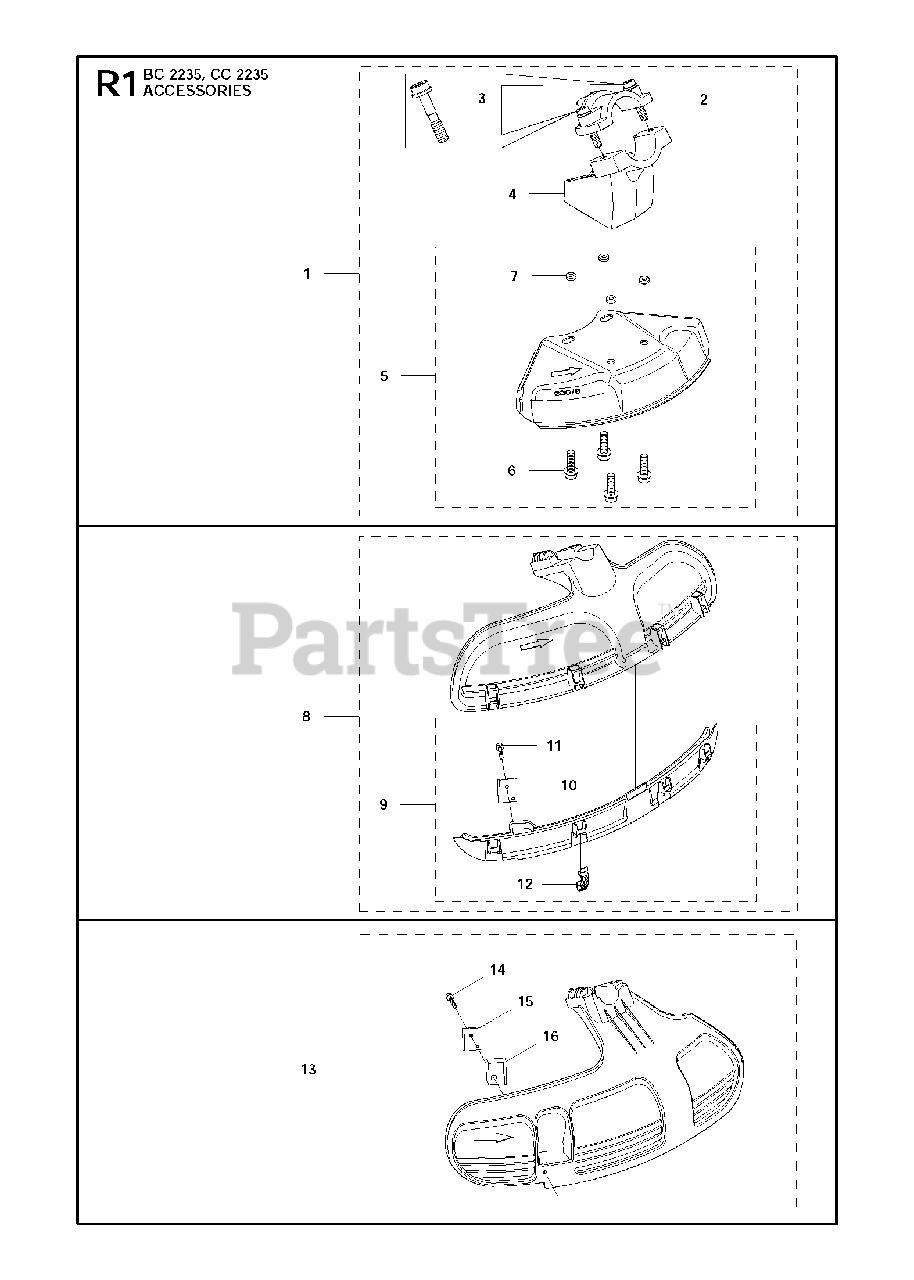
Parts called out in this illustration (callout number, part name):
2	CLAMP
3	SCREW IHSCFMO
4	ADAPTER
5	BLADE GUARD
6	SCREW
7	LOCKING NUT
8	COMBI PROTECTOR
9	PELMET
10	LINE CUTTER
11	SCREW
12	BUCKLE
13	TRIMMER GUARD
14	SCREW
15	LINE CUTTER
16	DISTANSBLOCK
